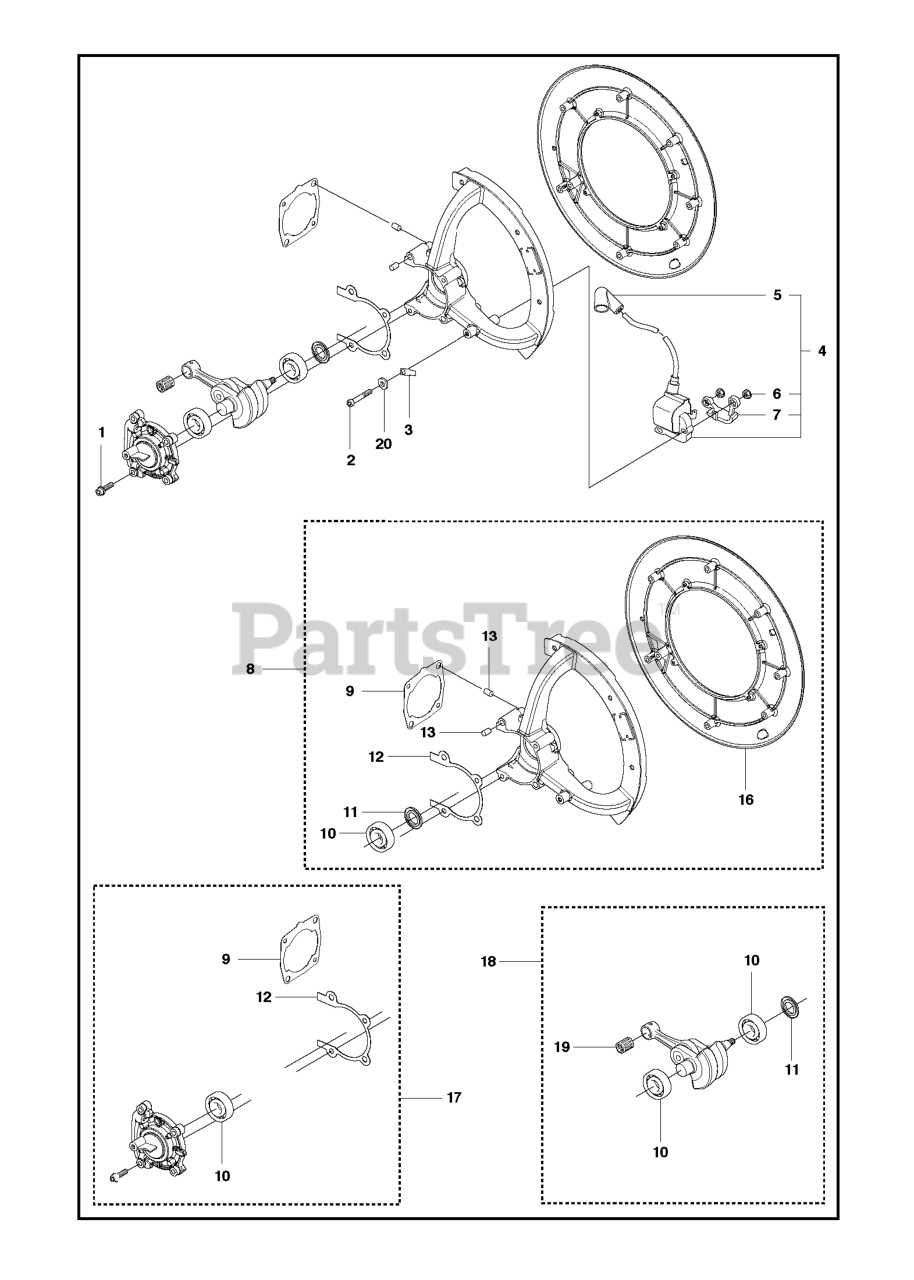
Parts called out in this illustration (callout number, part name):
1	SCREW
3	FLAT PIN
4	IGNITION SYSTEM
5	SPARK PLUG CONN. KIT
8	CRANKCASE KIT
10	BALL BEARING
18	CRANKSHAFT
19	NEEDLE BEARING PISTON PIN 12X1
20	WASHER 4.2X9
